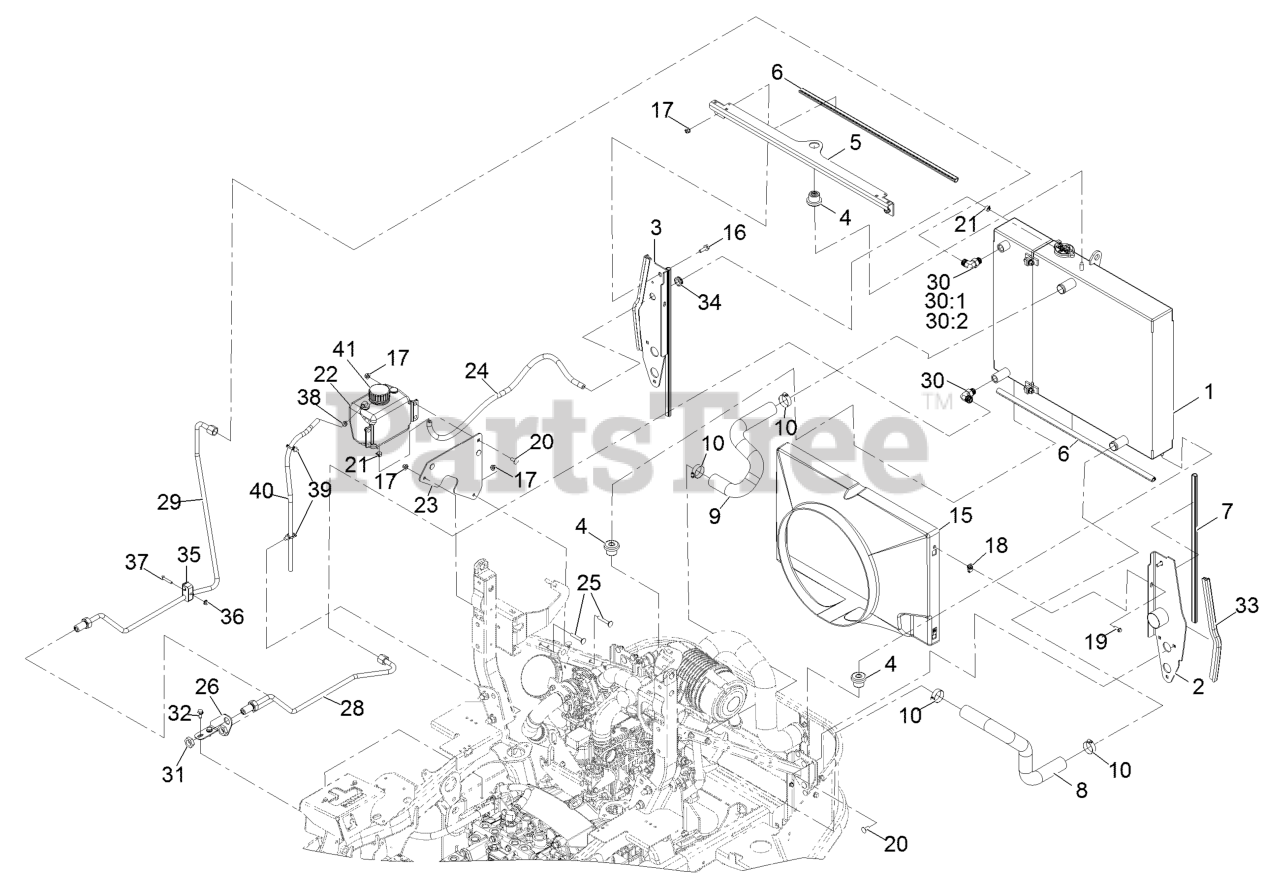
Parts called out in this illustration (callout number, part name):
1	Cooling ASM
2	Support-Radiator, LH
3	Support-Radiator, RH
4	Mount-Isolator
5	Bracket-Cooling, Top
6	Seal-Bulb
7	Seal-Bulb
8	Hose-Radiator, Lower
9	Hose-Radiator, Upper
10	Clamp-Hose
15	Shroud-Fan
16	Screw-HH Flg 5/16-18 X 1
17	Nut-Nyloc 5/16-18 Flg
18	Nut-Retainer-Panel 1/4-20
19	Screw-Machine 1/4-20 X 3/4
20	Bolt-Carriage 5/16-18 X 3/4 Short Neck
21	Clamp-Hose
22	Tank-Overflow, W/Cap
23	Bracket-Bottle
25	Bolt-Carriage 3/16-18 X 2
26	Bracket-Bulkhead
28	Hydraulic Tube ASM
29	Hydraulic Tube ASM
30	Fitting-Elbow, 90 DEG
30:1	O-Ring
30:2	O-Ring
31	Nut-Bulkhead
32	Screw-HWH 5/16-18 X 3/4 Tf
33	Seal-Bulb
34	Grommet
35	Clamp-Twin
36	Nut-Nyloc 1/4-20 Flg
37	Screw-HH 1/4-20 X 1 3/8
38	Clamp-Hose
39	Clip-Tie
40	Hose-Fuel
41	Cap-W/Tether, 2.25
